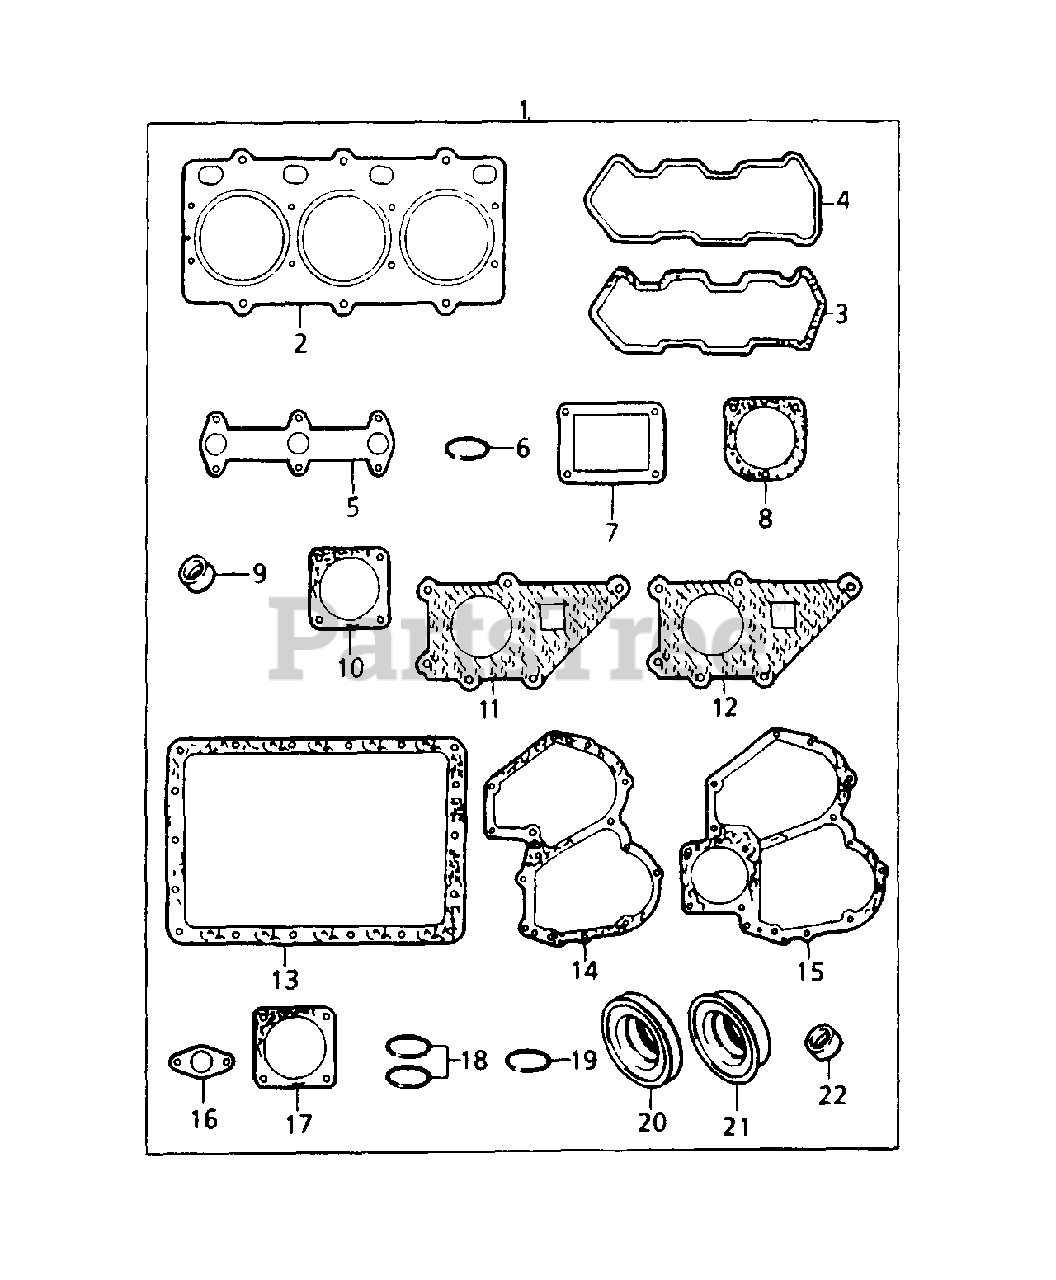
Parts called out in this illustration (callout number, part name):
1	KIT - gasket, complete
2	GASKET - head
3	GASKET - cover
4	GASKET - cover
5	GASKET - exhaust
6	"O" RING - cap
7	GASKET - fuel pump
8	GASKET - thermostat
9	SEAL - valve stem
10	GASKET
11	GASKET - water pump
12	GASKET - water pump
13	GASKET - sump, oil
14	GASKET - case
15	GASKET - plate
16	GASKET - fuel pump
17	GASKET - plate
18	"O" RING - oil tube
19	"O" RING - oil pipe
20	SEAL - case
21	SEAL - plate, rear
22	GASKET - atomizer
